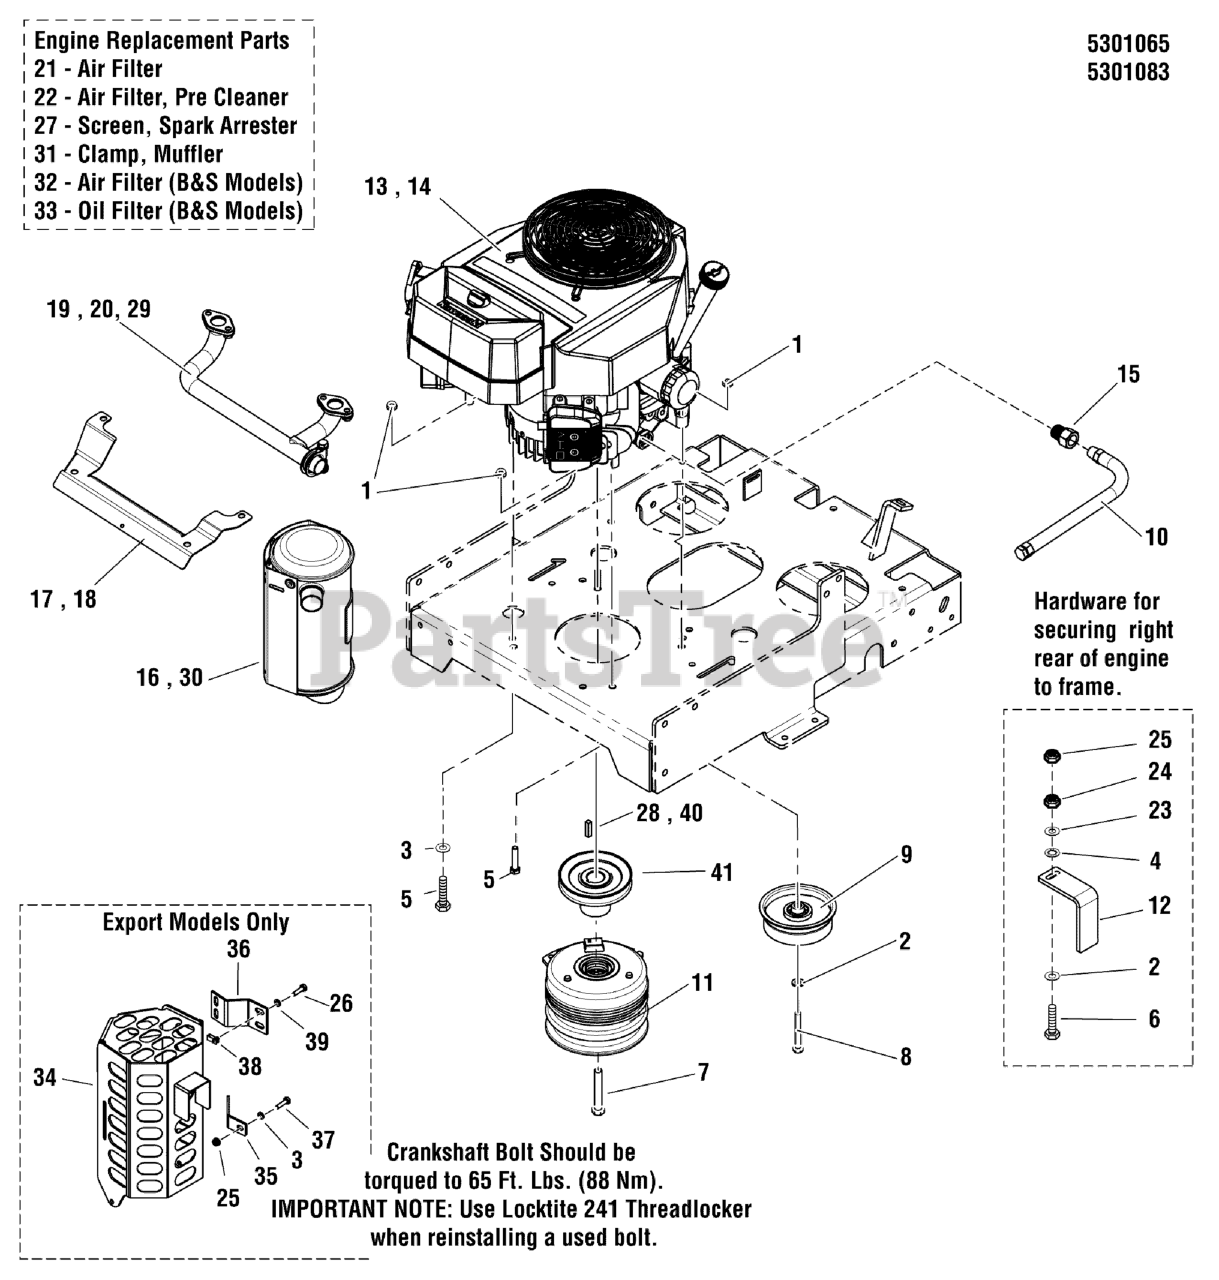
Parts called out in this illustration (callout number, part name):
1	NUT, 5/16-18 HEX NYLON LOCK
2	WASHER, 5/16 GD.9 FLAT
3	WASHER, 5/16" SAE
4	WASHER, 5/16" INT. TOOTH LOCK
5	BOLT, 5/16-18 X 1-3/4" GD5 YZ
6	BOLT, 5/16-18 X 2-1/4" GD5 YZ
7	BOLT, CRANKSHAFT, 7/16-20 X 3, GD8
8	BOLT, 5/16-18 X 2-1/2" GD5 YZ
9	PULLEY, IDLER, SINGLE FLANGE
10	HOSE, OIL DRAIN
11	CLUTCH, WARNER, 125 ft lbs - 1"
12	ANCHOR, CLUTCH - BLK
13	ENGINE, KAWASAKI, FH SERIES
14	ENGINE, BRIGGS, VANGUARD, 305776 SERIES
15	ADAPTER, OIL DRAIN
16	MUFFLER, KAWA
17	HEAT SHIELD, EXHAUST MANIFOLD (SV)
18	HEAT SHIELD, EXHAUST MANIFOLD (SV)
19	MANIFOLD. EXHAUST (SV)
20	MANIFOLD. EXHAUST (SV)
21	AIR FILTER (SV)
22	PRE AIR FILTER (SV)
23	WASHER, 5/16 LOCK CZ
24	NUT, 5/16-18 HEX
25	NUT, 5/16-18 HEX NYLOCK FLANGE
26	BOLT, 1/4-20 X 3/4 GD5 YZ
27	SCREEN, SPARK ARRESTER
28	KEY, 1/4 SQ. X 3/4
29	MANIFOLD, EXHAUST
30	MUFFLER, EXHAUST
31	MUFFLER CLAMP
32	AIR FILTER
33	OIL FILTER
34	WELD, MUFFLER GUARD
35	BRACKET, MUFFLER GUARD
36	BRACKET, MUFFLER GUARD
37	BOLT, 5/16-18 X 1 GD5 YZ
38	BODY CLIP, 1/4-20 X 1/2 DEEP
39	WASHER, 1/4 SAE
40	KEY, 1/4 SQ X 1
41	PULLEY, CRANKSHAFT, 1.0005 ID X 4.25 OD
